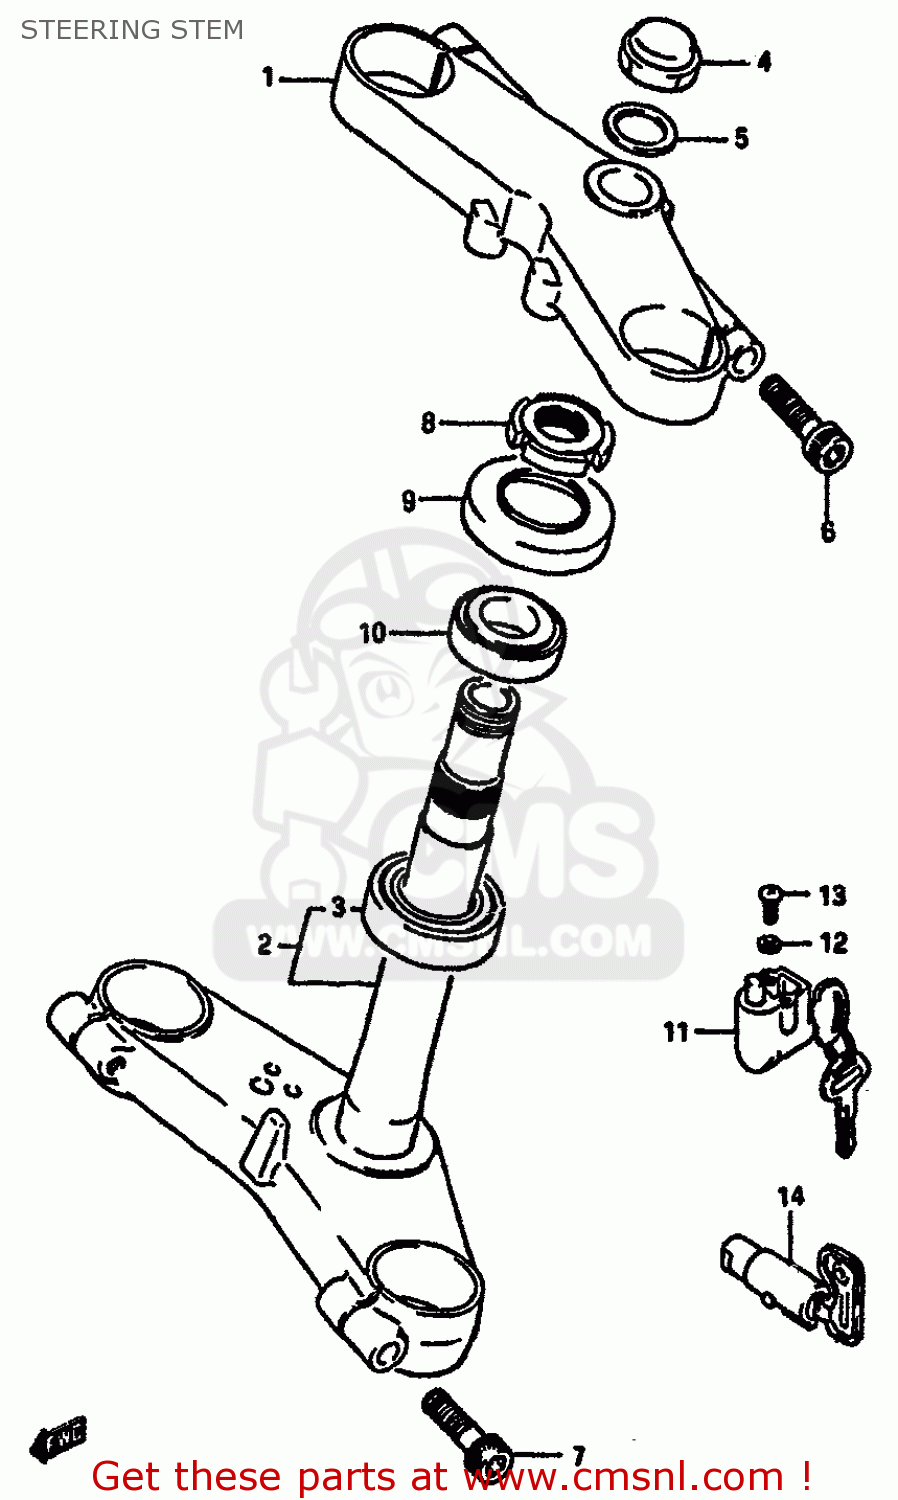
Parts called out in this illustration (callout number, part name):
1	STEM HEAD,STEERING
2	STEM,STEERING
3	BEARING
4	NUT,STEM HEAD
5	WASHER,STEERING STEM
6	BOLT,FORK INNER TUBE FITTING
7	BOLT ,10X40
8	NUT,STEERING STEM(25X44X10)
9	DUST SEAL,STEERING UPR
10	TAPER,ROLLER BEARING
11	LOCK ASSY,STEERING
12	LOCK WASHER
13	SCREW 5X20
14	LOCK ASSEMBLY,STEERING (NEI
